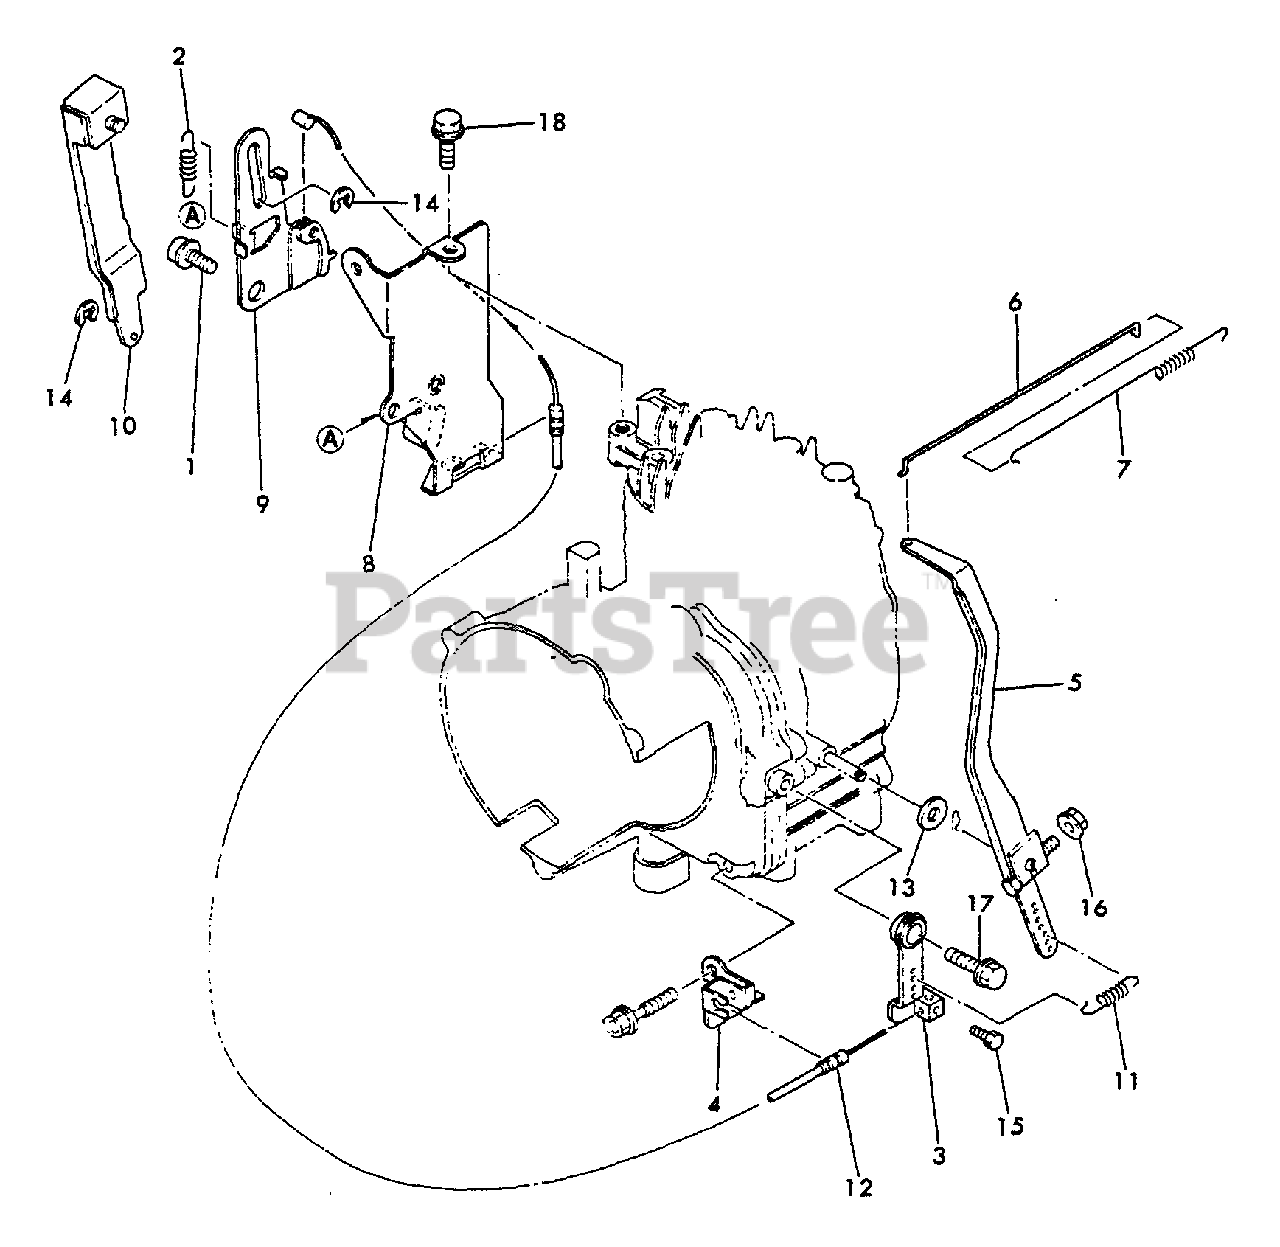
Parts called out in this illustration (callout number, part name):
1	SCREW M6×10
2	SPRING, REGULATOR
3	HANDLE ASSY
4	WIRE HOLDER
5	LEVER, GOVERNOR
6	LINK, THROTTLE
7	SPRING, TENSION
8	BRACKET, CONT. LEVER
9	LEVER, CONTROL
10	LEVER, CONT. SHIFT
11	SPRING, CONT. LEVER
12	THROTTLE CABLE ASSY
13	WASHER
14	RING, RETAINING - 5
15	BOLT - 4×8 -- PLATED
16	U-NUT M6
17	BOLT - 6×8 -- PLATED
18	BOLT - 6×8 -- PLATED
